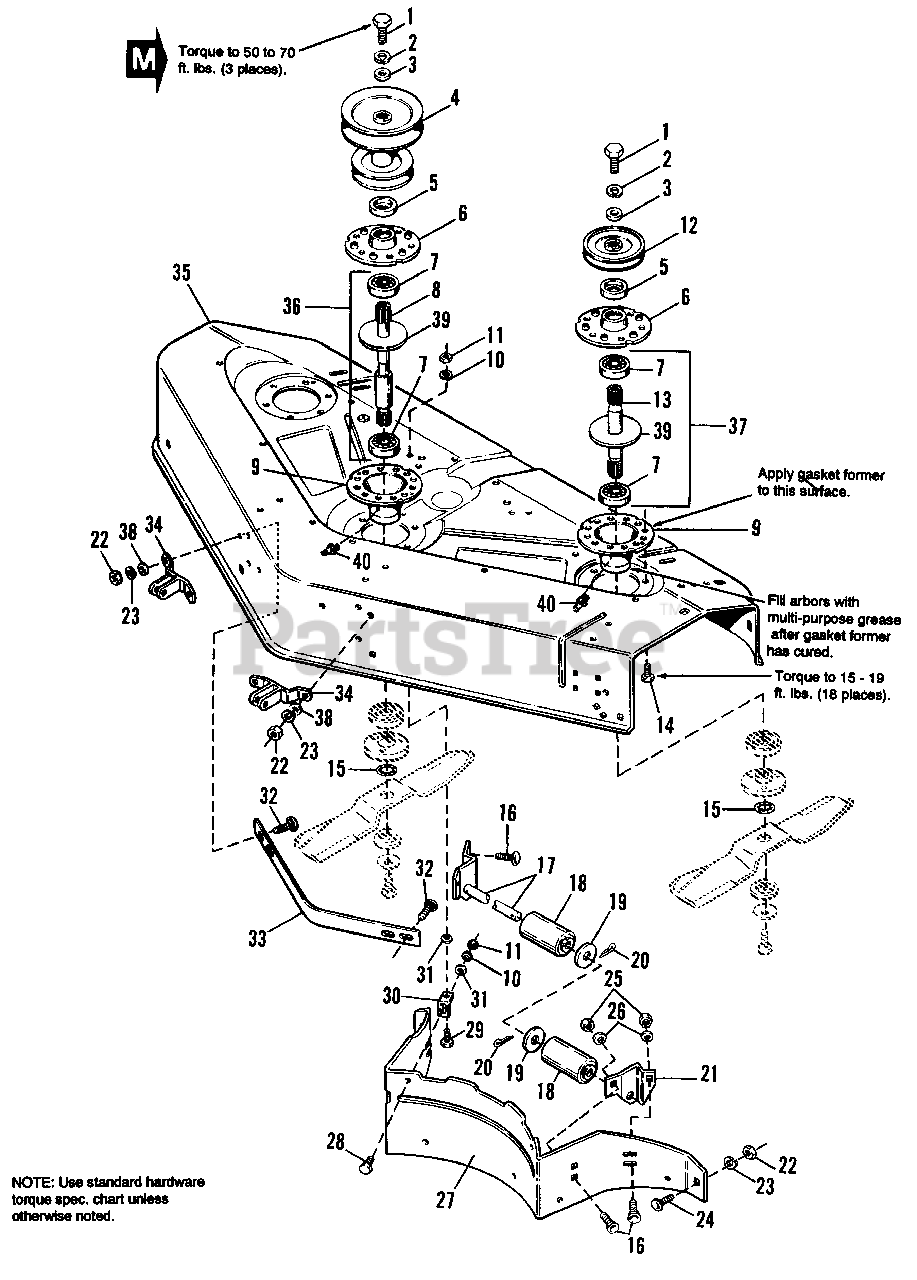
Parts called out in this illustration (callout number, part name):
1	CAPSCREW, Hex Hd., 7/16-14 x 1-1/4
2	LOCKWASHER, 7/16
3	WASHER, 29/64 x 1-1/4 x 1/4
4	PULLEY ASSY., 42" Mower
5	SHIELD, Bearing Upper, Arbor
6	HOUSING, Arbor, Top
8	SHAFT, Arbor, Center
9	HOUSING, Arbor Bottom
10	LOCKWASHER, 1/4
11	NUT, Hex, Full, 1/4-20
12	PULLEY ASSY., Deck Drive
13	SHAFT, Arbor, Side (Incl. Ref. No. 15, Qty. 1)
14	SCREW, Hex, Washer Hd., Taptite, 5/16-18 x 3/4
15	RING, Self-Locking
16	CARRIAGE BOLT, 5/16-18 x 3/4
17	BRACKET & SHAFT ASSY., 42" Mower
17	BRACKET & SHAFT ASSY., 48" Mower
19	WASHER, 21/32
20	PIN, Cotter
21	BRACKET, Roller, L.H.
22	NUT, Hex, Full, 3/8-16
23	LOCKWASHER 3/8
24	CARRIAGE BOLT, 3/8-16 x 1
25	NUT, Hex, Full, 5/16-18
26	LOCKWASHER, 5/16
27	BAFFLE, 42" Mower
27	BAFFLE, 48" Mower
28	CAPSCREW, Hex Hd., 1/4-20 x 5/8
29	SCREW, Thread Forming, 1/4-20 x 3/4
30	CLIP,. Baffle
31	WASHER, Plain, 9/32
32	CARRIAGE BOLT, 3/8-16 x 1-1/4
33	BAR, Reinforcement
34	BRACKET ASSY., Front
35	HOUSING, 42" Mower (Orange)
35	HOUSING, 42" Mower (Black)
35	HOUSING, 48" Mower (Orange)
35	HOUSING, 48" Mower (Black)
36	SHAFT & BEARING ASSY., Center (Incl. Ref. Nos. 7 & 8)
37	SHAFT & BEARING ASSY., Side (Incl. Ref. Nos. 7 & 13)
38	WASHER, 13/32 I.D.
39	GASKET, Foam
40	PULLEY ASSY., 48" Mower
40	FITTING, Grease
